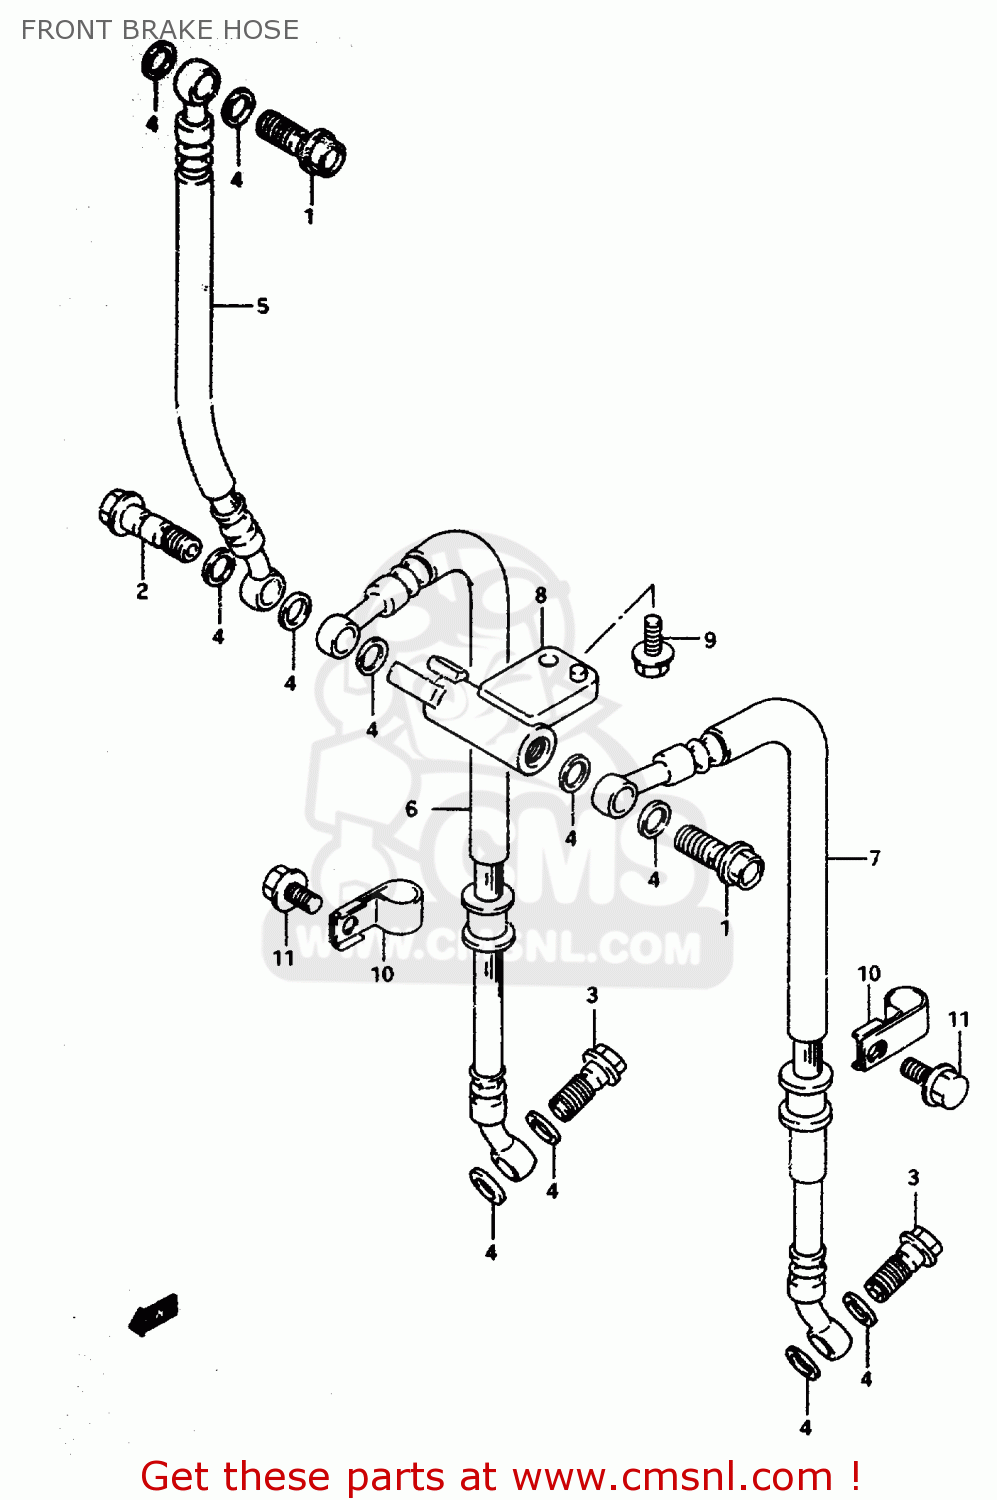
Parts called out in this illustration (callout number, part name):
1	BOLT UNION
2	BOLT UNION
3	BOLT UNION
4	WASHER(10X15X1.5)
5	HOSE,FR BRAKE NO.1
6	HOSE,FR BRAKE NO.2,R
7	HOSE COMP,FRONT BRAKE
8	JOINT,BRAKE HOSE
9	BOLT
10	CLAMP,FR BRAKE HOSE NO.2
11	BOLT
